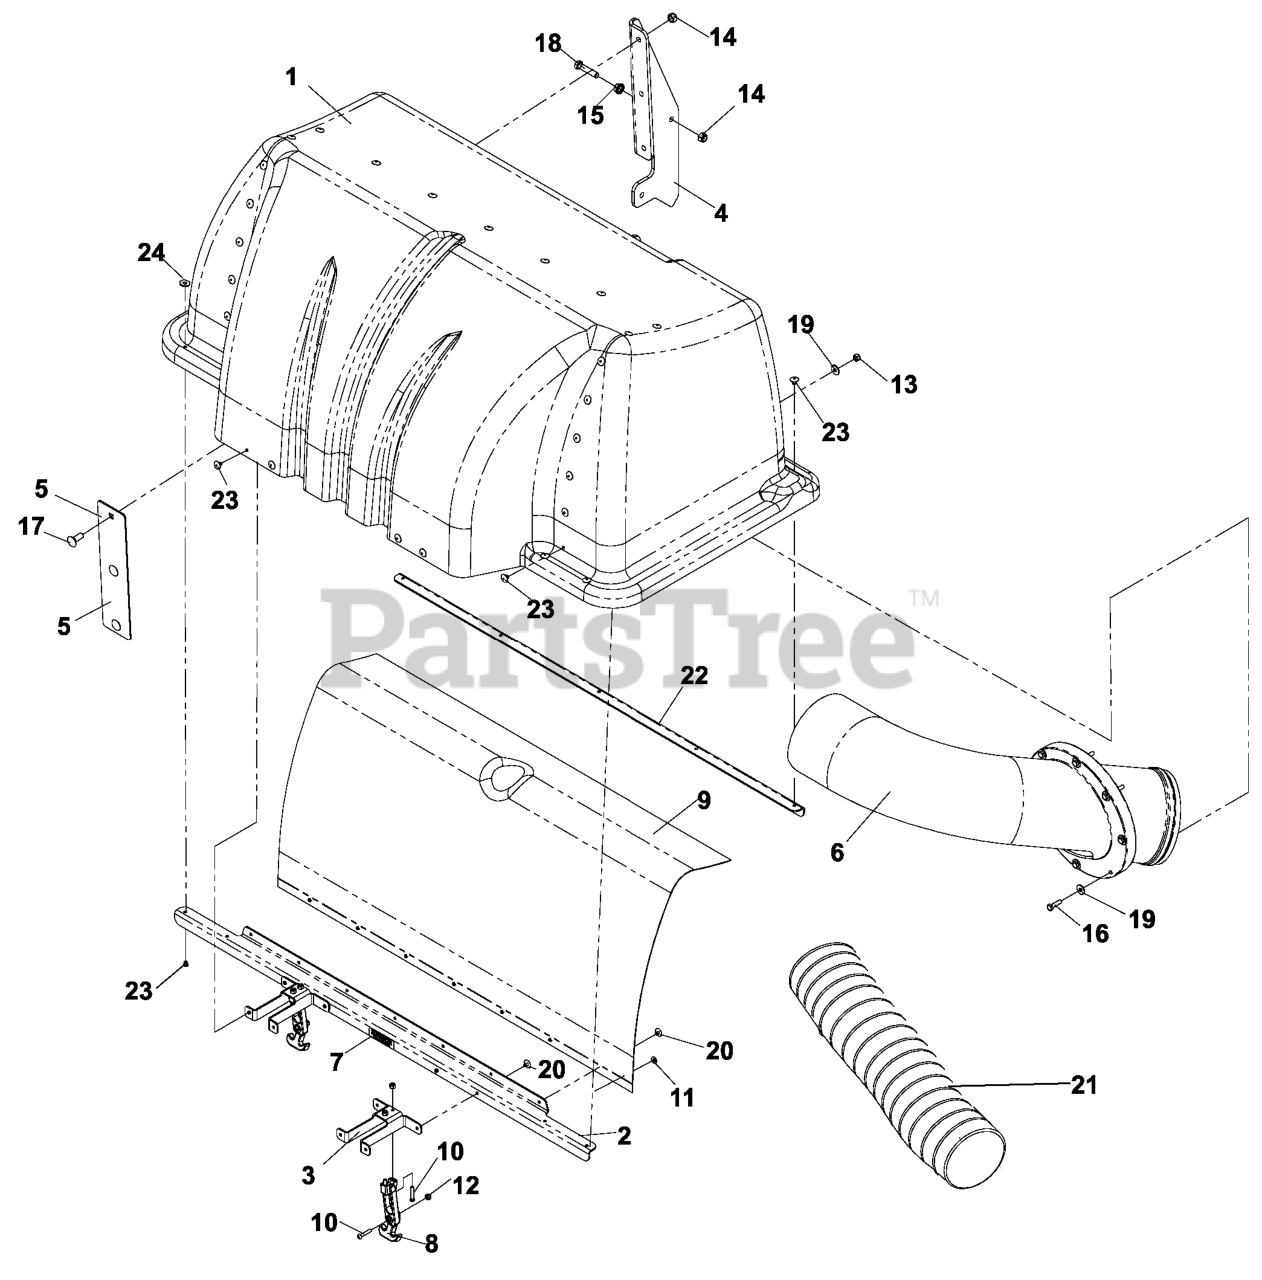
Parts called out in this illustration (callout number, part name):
2	HOOD SUPPORT
3	SUPPORT, DRAW LATCH
4	HOOD HINGE
5	MOUNT PLATE
7	DECAL, VENTILATION
8	DRAW LATCH, FLEXIBLE T-HANDLE
9	MESH, POLY DIAMOND
10	SCR, #10-24 X 1-1/8
11	WASHER #10
12	NUT 10-24 NYLOC
13	NUT.1/4-20.HEX.NYLOC.ZD
14	NUT 3/8-16 NYLOC
15	NUT 3/8C WHIZ
16	BOLT 1/4C X 1 3/4
17	RHSNB 3/8C X 1
18	HCS 3/8-16 X 1 3/4 GR5
19	WASHER 1/4 FLAT
20	RIVET E/16 X 1/4 LG FLG
21	HOSE 7 X 58 CLEAR
22	HOOD SUPPORT, REAR
23	RIVERT, 3/16, STAVEX
24	WASHER, #10 MACH SCR BLK OX
